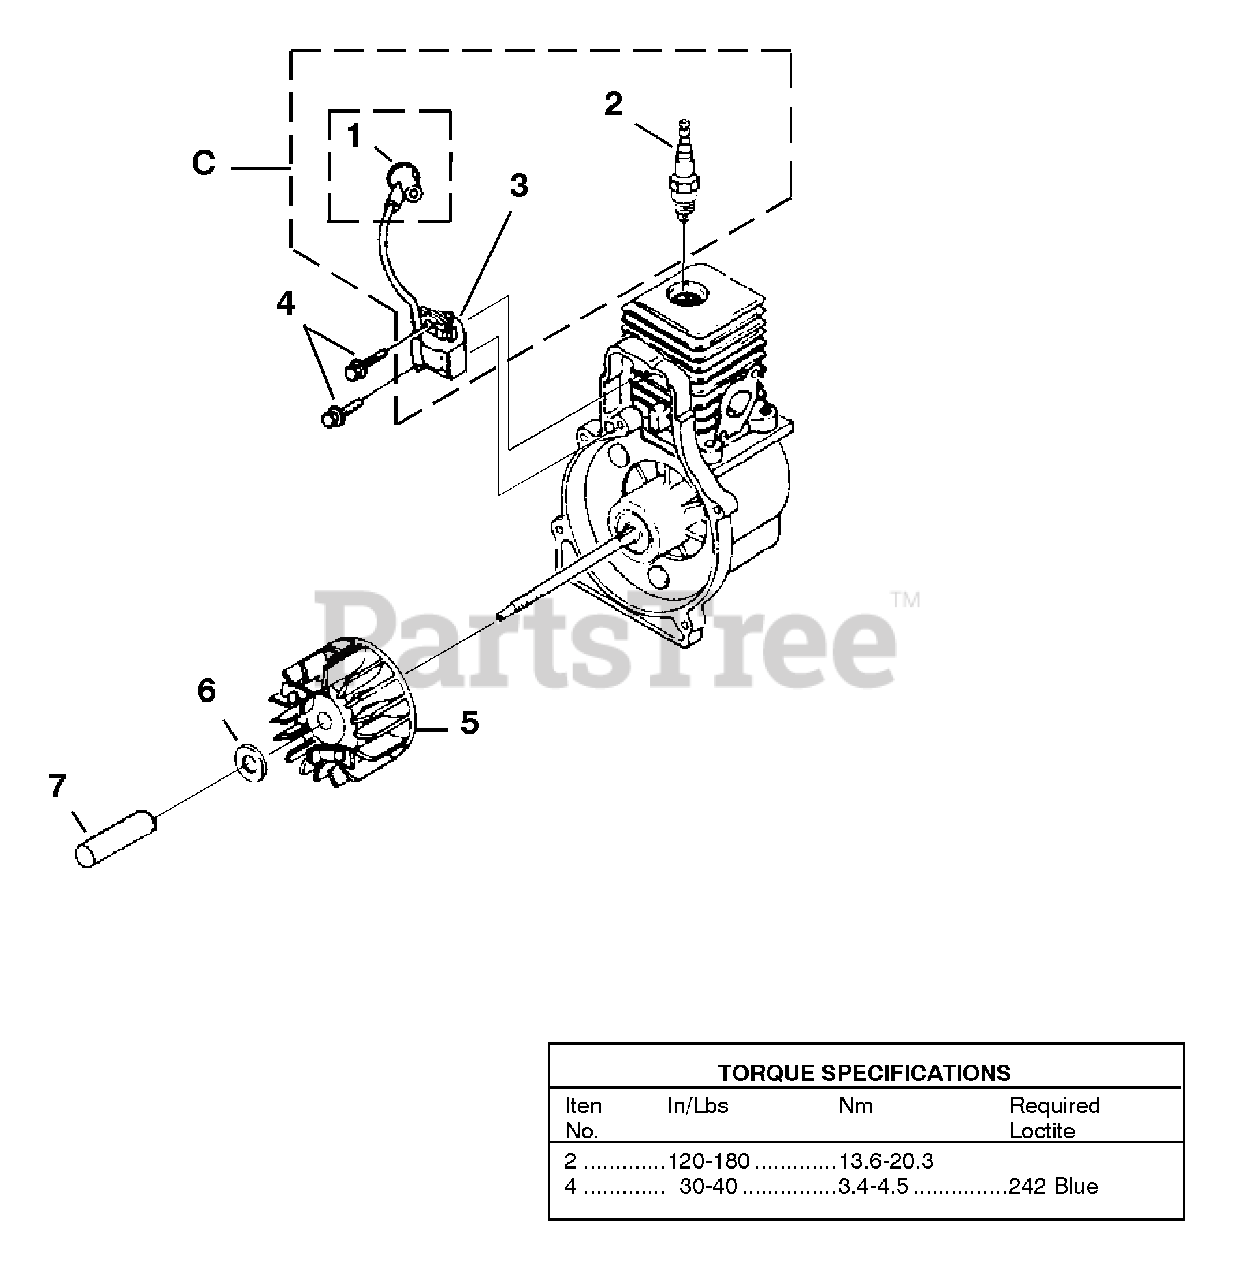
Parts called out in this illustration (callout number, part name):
1	TERMINAL and COVER
2	SPARK PLUG
3	IGNITION Module
4	SCREW-Thread Form. (8-32 x 1")
5	ROTOR & STARTER PAWLS
6	WASHER-Flat
7	SPACER-Fan
C	IGNITION KIT w/Module
